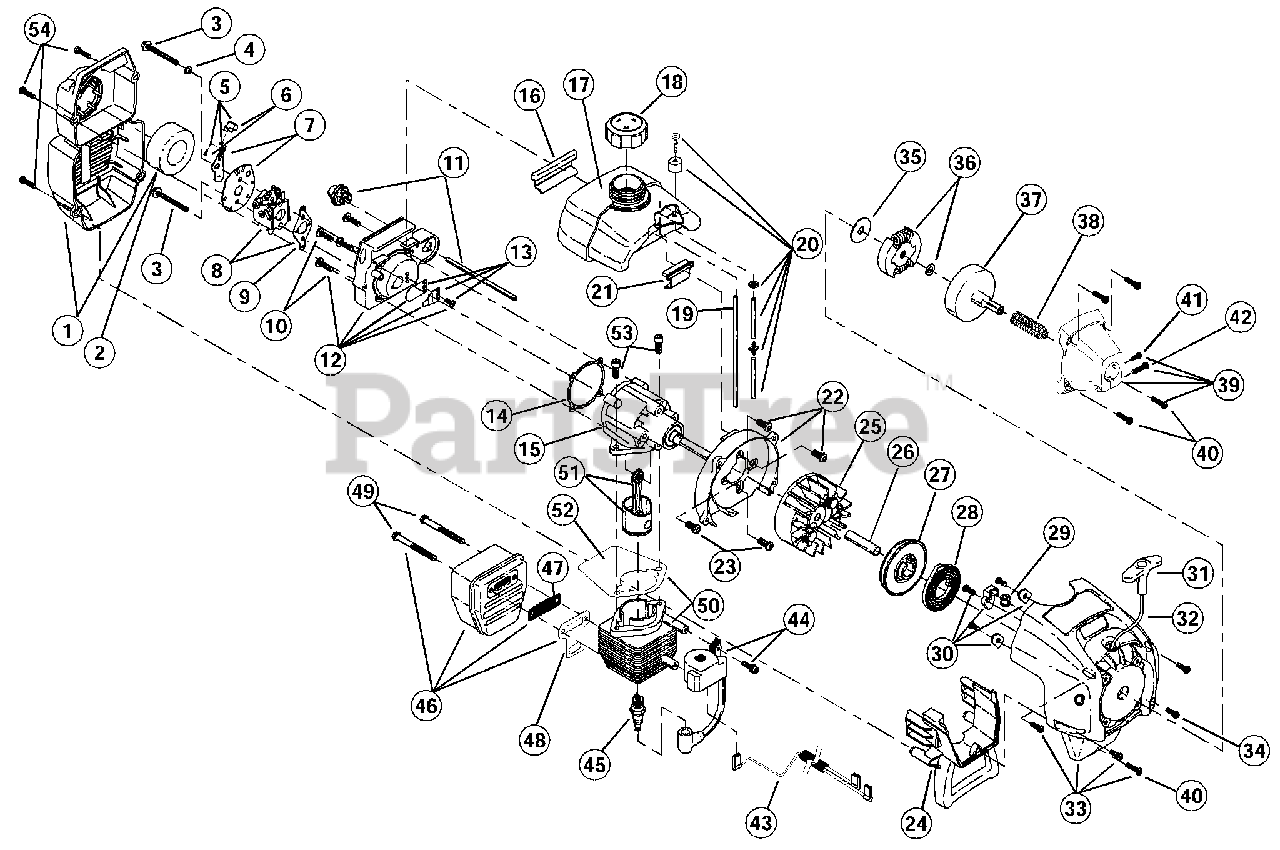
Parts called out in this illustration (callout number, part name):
1	Air Cleaner/Muffler Cover Assembly
2	Air Cleaner Filter
3	Carburetor Mounting Screw Assembly
4	Wavey Washer
5	Choke Lever Assembly
6	Choke Knob and Screw
7	Choke Lever and Plate
8	Carburetor Assembly
9	Carburetor Gasket
10	Carb Mount Screw
11	Primer and Hose Assembly
12	Carb Mount Assembly
13	Reed Assembly
14	Crankcase Gasket
15	Crank Case Service Assembly
16	Rear Mounting Pad
17	Fuel Tank Assembly
18	Fuel Cap Assembly
19	Fuel Return Line
20	Fuel Line Assembly
21	Front Mounting Pad
22	Shroud Assembly
23	Shroud Screw
24	Shroud Extension and Stand
25	Flywheel Assembly
27	Recoil Pulley Assembly
28	Recoil Spring
29	Rope Guide
30	Pulley Retainer Assembly
31	Pull Handle
33	Starter Housing Assembly
34	Housing Screw
35	Clutch Washer
36	Clutch Rotor Assembly
37	Clutch Drum Assembly
39	Clutch Cover Assembly
40	Cover Screw
41	Anti-Rotation Screw
42	Clamping Screw
43	Wire Leads and Sleeve
44	Module Assembly
45	Spark Plug
46	Muffler Assembly
47	Spark Arrestor Screen
48	Exhaust Gasket
49	Muffler Mounting Bolt
50	Cylinder Assembly
51	Piston and Rod Assembly
52	Cylinder Gasket
53	Cylinder Bolt
